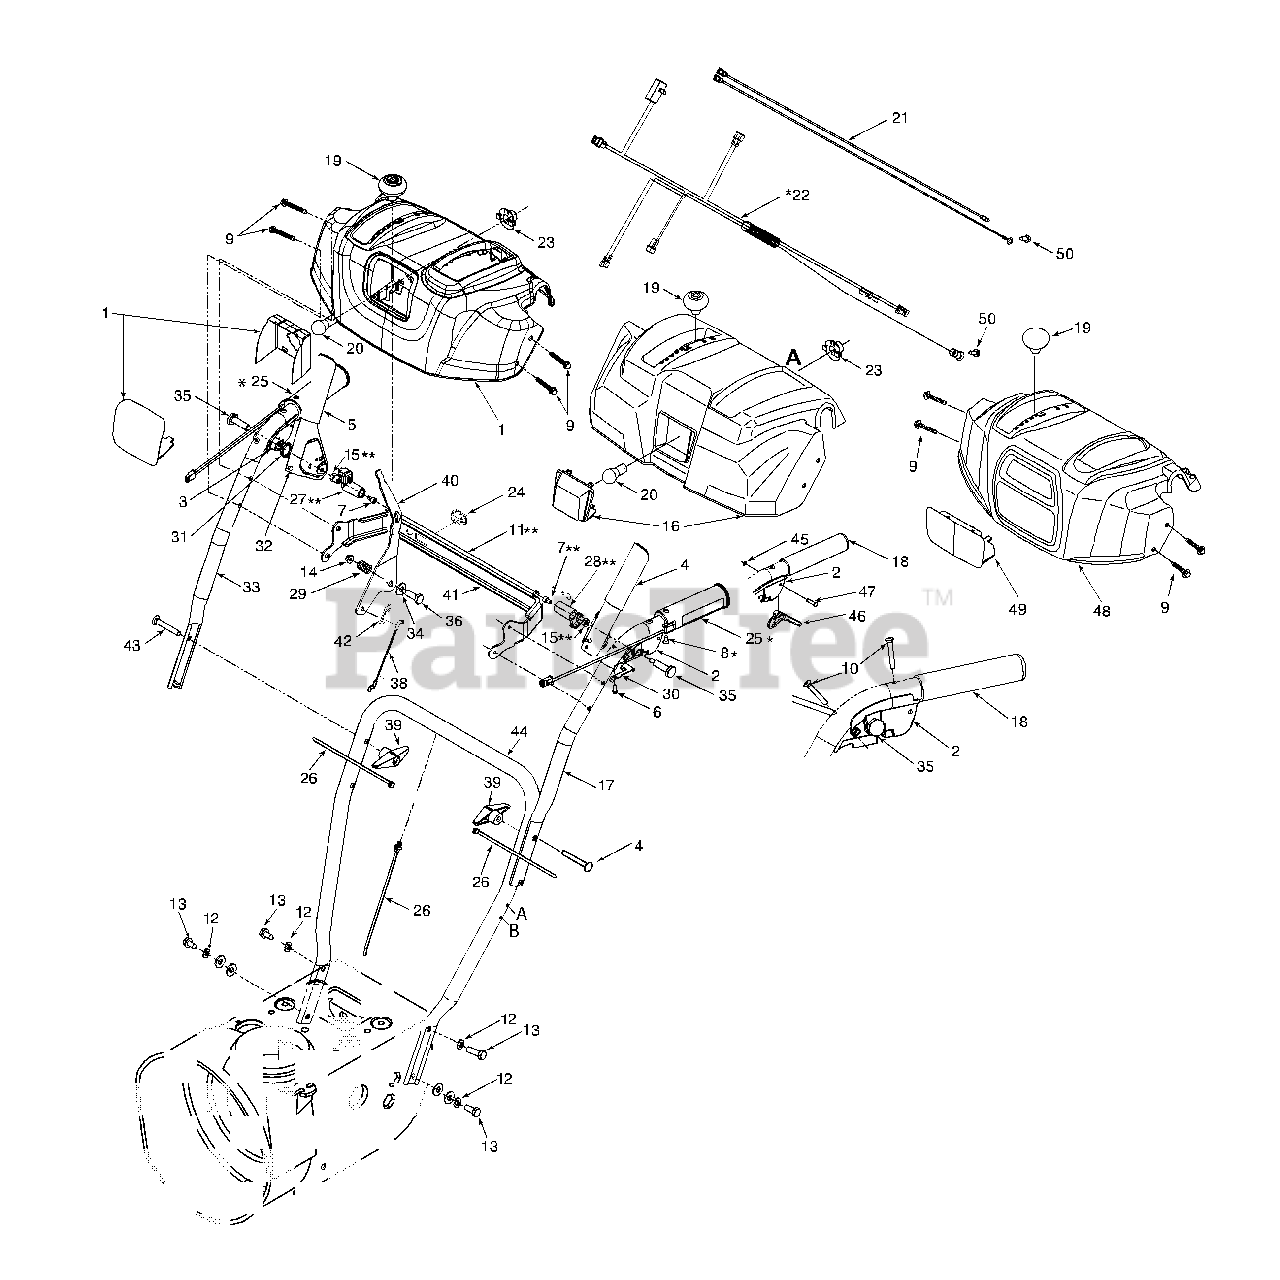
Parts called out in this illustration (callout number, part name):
1	Handle Panel Ass’y - Yellow
1	Handle Panel Ass’y - Black
1	Handle Panel Ass’y-Black w/Chute Control
1	Handle Panel Ass’y-Grey w/Chute Control
2	LH Clutch Lock Handle Ass’y
3	RH Clutch Lock Handle Ass’y
4	Engagement Handle Assembly LH - Black
5	Engagement Handle Assembly RH - Black
6	Screw #8-16 x .50
7	Hex Cap Socket Screw 1/4-20 x .5
8	Oval HD C-Sunk Scr #10 x 5/8
9	Hex TT-Tap Scr 1/4-20 x 1.625
10	Oval C-Sunk Hd Screw 10-24 x 1.375
12	Lockwasher 5/16 ID
13	Hex TT Screw 5/16-18 x .75 Gr. 5 Patch
14	Hex L-Flanged Nut 1/4-20 Gr. F Nylon
15	Hex Shoulder Nut 1/4-20
15	Hex L-Flg Nut 1/4-20 Gr. F Nylon
16	Handle Panel Ass’y - Troy-Bilt
17	Upper Handle LH - Black
19	Shift Knob - Yellow
20	Lamp (179 cc/208 cc engines)
20	Lamp (277 cc/347 cc & 420 cc engines)
22	Heated Grip Wire Harness
23	Socket
26	Cable Tie (w/plug)
26	Cable Tie (w/heated grips)
27	Lock Plate
28	Clutch Lock Cam
29	Compression Spring .38 ID x .88 Lg
30	Spring: Clutch Lock
31	Torsion Spring .8156 x .3038
32	Rubber Bumper
33	Upper Handle RH - Black
34	Flat Washer .38 ID x .87 OD x .09
35	Shoulder Screw .437 x 1.345: 1/4-20
36	Shoulder Screw .374 Dia. x 1.05 Lg.
37	Flat Washer .344 ID x .688 OD x .065
38	Selector Speed Cable
39	Handle Knob Assembly
41	Panel Support
42	Cotter Pin
43	Carriage Bolt 5/16-18 x 2.25
44	Lower Handle - Black
46	Steering Control - Black
48	Handle Panel Ass’y - Red (w/lens)
50	Hex Wash S-Tapp Scr 1/4-20 x .50
